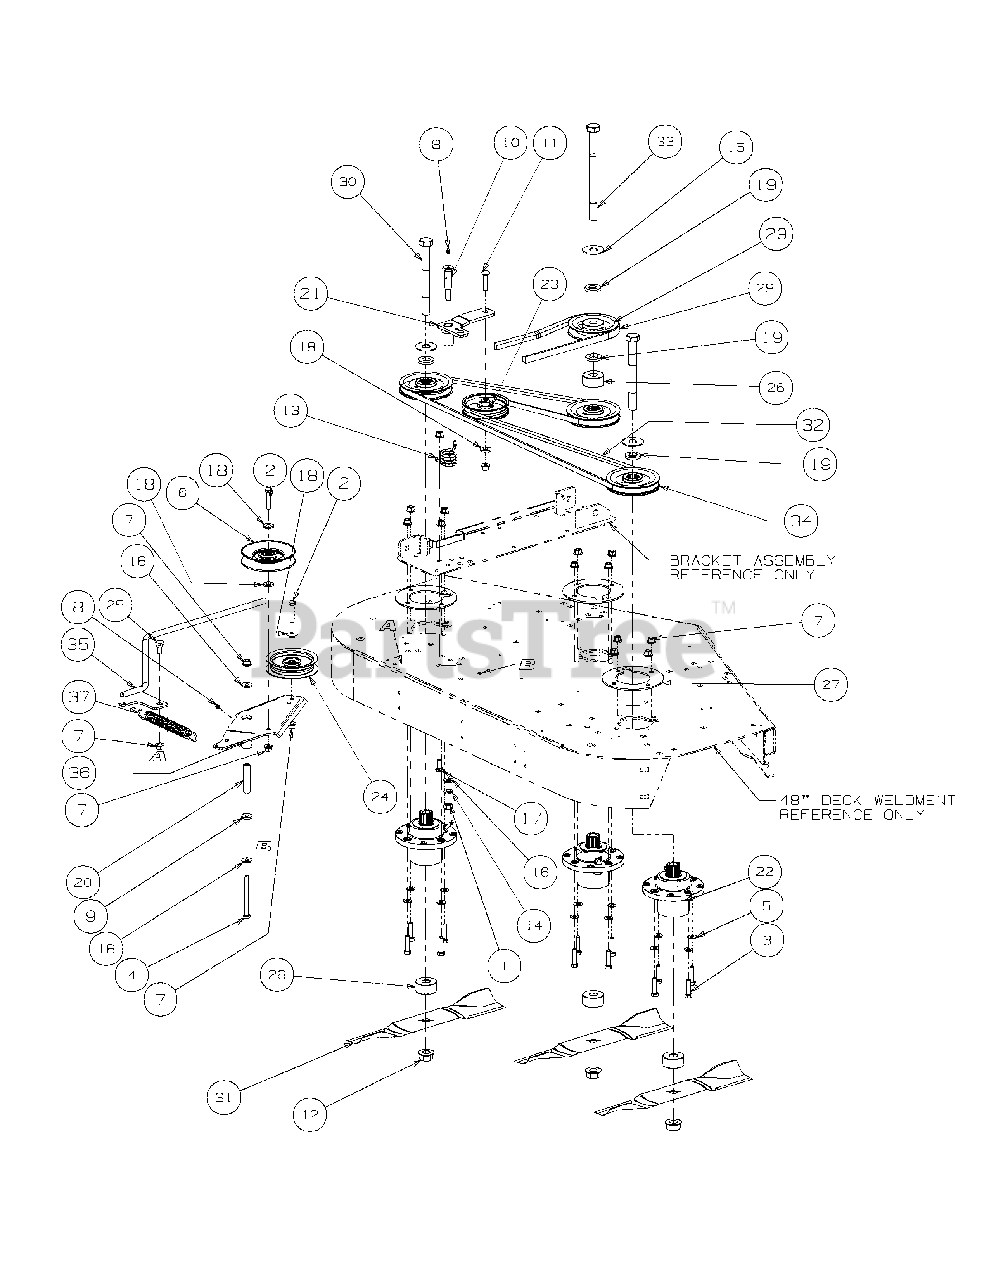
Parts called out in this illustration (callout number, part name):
1	Hex Nut, 7/16-14
2	Hex Cap Screw, 3/8-16 x 1-1/4
3	Hex Cap Screw, 3/8-16 x 1-1/2
4	Hex Cap Screw, 3/8-16, 4.00
5	Flat Washer, 3/8
6	Idler Pulley, 5.06 Dia.
7	Hex Nut, Flange Lock, 3/8-16
8	Grease Fitting, 1/4-28 x 3/16
9	Idler Washer
10	Shoulder Screw, 7/16-14
11	Hex Carriage Screw, 3/8-16, 1.75
12	Hex Flange Nut, 3/4-16
13	Torsion Idler Spring
14	Lock Washer, 7/16
15	Flat Washer, .781 ID, 2.00 OD, .105
16	Flat Washer, .469 ID, .875 OD, .105
17	Carriage Bolt, 3/8-16 x 1
18	Flat Washer, .406 ID, 1.0 OD, .105
19	Spacer, .812 ID x .218 LG
20	Spacer, .39 ID x .625 OD x 2.75
21	Idler Arm Assembly, Deck Spindle includes:
22	Aluminum Spindle Assembly
23	Flat Pulley
24	PULLEY-FLAT IDLER 4.875
25	Shoulder Screw, .50 x .27 Lg., 3/8-16
26	Spacer, .760 ID x 2.000 OD x 1.1
27	Spindle, Aluminum Cast Support Plate
28	V-Belt, B Section x 83.2
29	V-Pulley, 4.75 OD
30	Hex Cap Screw, 3/4-16, 7.00
31	Blade, 17.0, Hi-Lift, 0.756 ID
32	V-Belt, A Section x 105.3
33	Hex Cap Screw, 3/4-16, 9.00
34	V-Pulley, 5.00 OD
35	Spring Tension Rod Assembly
36	Idler Arm Assembly Service Kit
36	Bearing for idler arm
37	Spring Extension, .94 OD x 7.57
